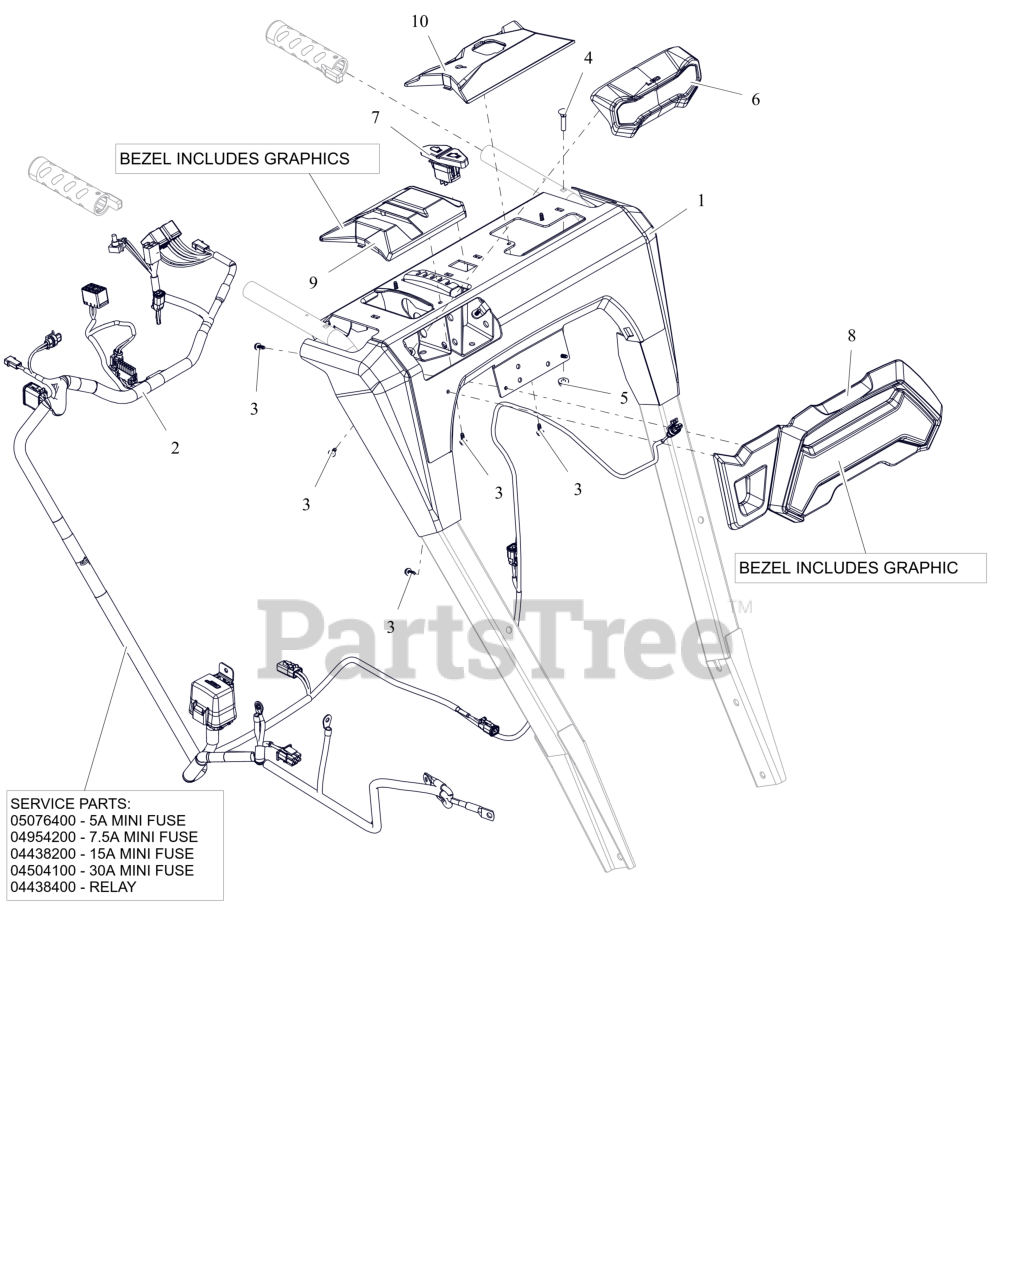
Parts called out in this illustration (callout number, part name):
1	PANEL, DASH-HYD EFI ECR W/DECAL
2	HARNESS- WIRE-12V TRK ACT
2	FUSE, 5 AMP MINI-ATC
2	FUSE, 7.5 AMP MINI-ATC
2	Fuse, 15 AMP MINI-ATC
2	FUSE,30 AMP MINI-ATC
2	RELAY,MICRO5 TERML W/RESISTOR
3	SCR, PLASTIC #10X.50
4	BLT-RDHDXLSQNK.25-20X1.25 G5ZC
5	NUT-LK-CTR-FLG .25-20 ZC120
6	HEADLIGHT ASM- LED
7	SWITCH- ROCKER SPST-ON/OFF
8	BEZEL- LARGE - PROFESSIONAL
9	BEZEL, SHIFT HYDRO TRACK DECAL
10	BEZEL, OPERATOR EFI DECAL
